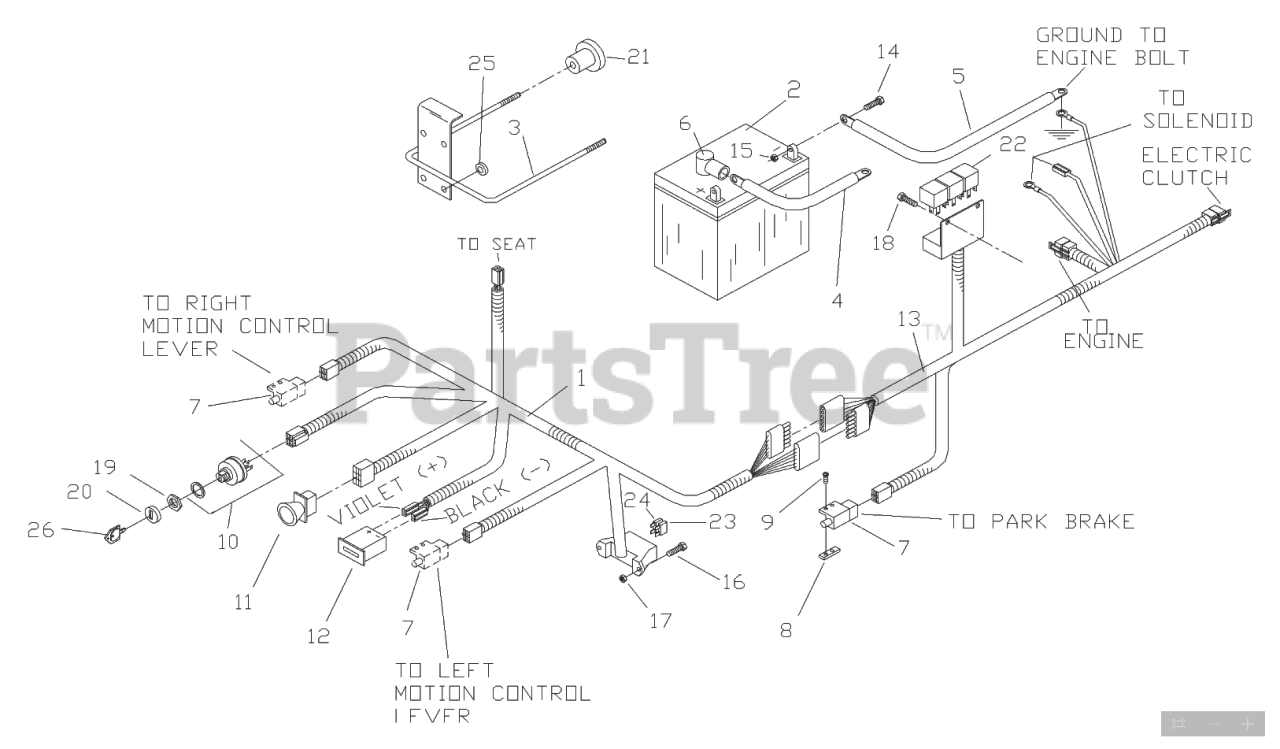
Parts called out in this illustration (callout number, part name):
1	CONSOLE HARNESS
2	12V BATTERY
3	BATTERY HOLD DOWN
4	POSITIVE CABLE
5	NEGITIVE CABLE
7	INTERLOCK SWITCH
8	TAPPED PLATE
9	#10-24 X 5/8
10	IGNITION SWITCH ASSY.
11	PTO SWITCH
12	HOUR METER
13	FRAME HARNESS
14	HCS 5/16C X 3/4
15	NUT 5/16C CTR. LOCK
16	#10-24 X 7/8 SCREW
17	#10-24 HEX NYLOC NUT
18	SELF TAPPING SCREW
19	NUT IGN. SWITCH
20	CAP, IGN. SWITCH
23	7.5 AMP 32V ATO FUSE
24	20.0 AMP 32V ATO FUSE
26	KEY, PADDED
